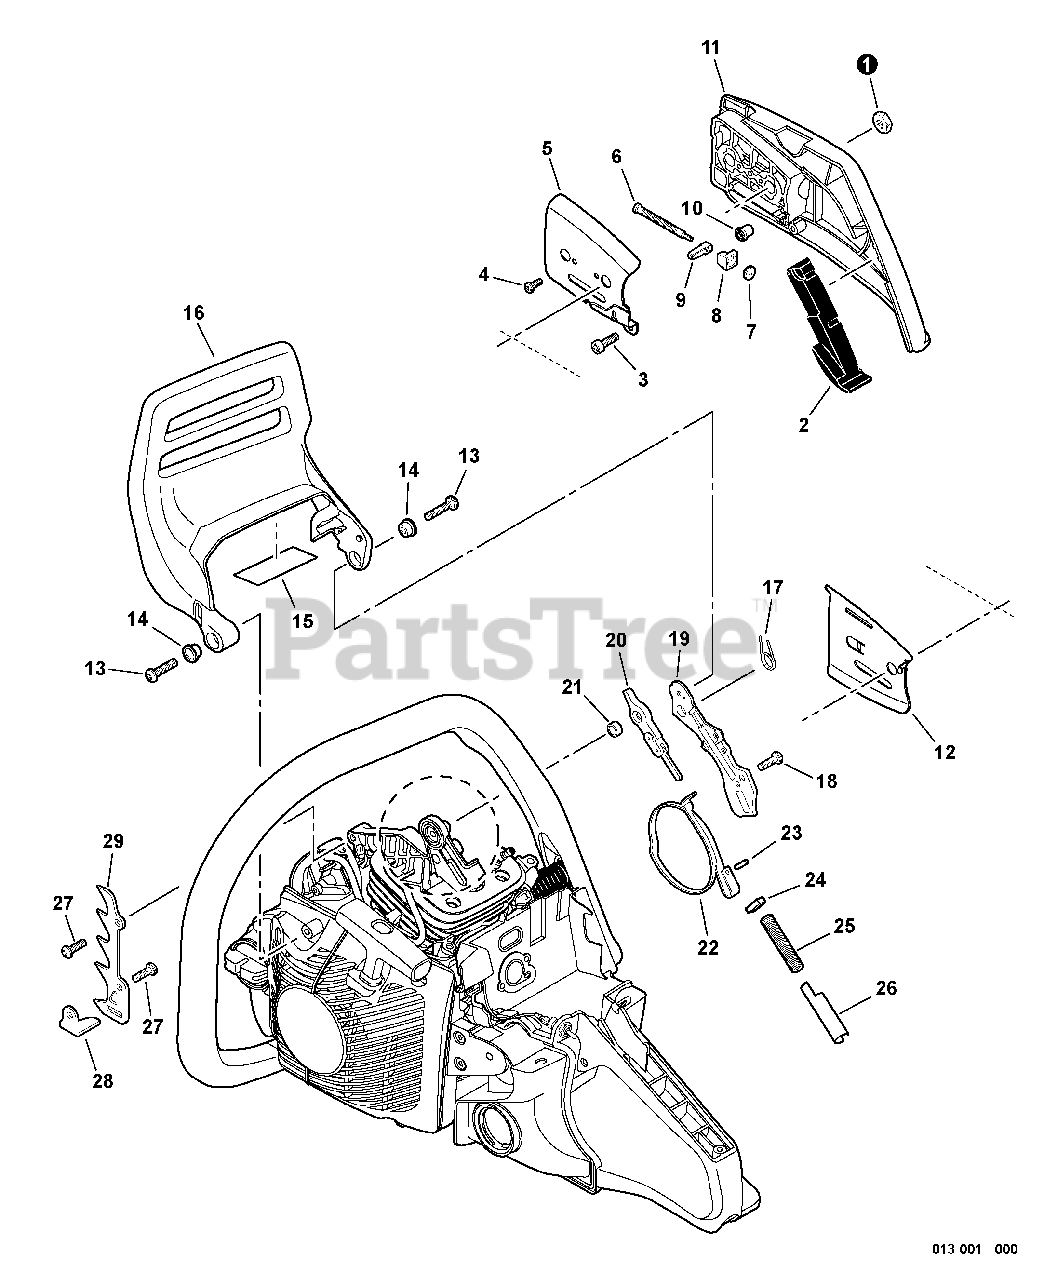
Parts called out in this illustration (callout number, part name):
1	NUT - 8
2	CUSHION
3	SCREW - 4X12
4	SCREW - 3X5
5	PLATE, GUIDE - OUTER
6	SCREW, TENSIONER
7	GEAR - BEVEL
8	COLLAR - 8
9	TENSIONER, CHAIN
10	GEAR - PINION
11	GUARD, SPROCKET
12	PLATE, GUIDE - INNER
13	SCREW - 5X16
15	DEFLECTOR, HEAT
16	LEVER, BRAKE
18	SCREW - 5X16
19	COVER, BRAKE
20	CONNECTOR, BRAKE
22	BAND, BRAKE
26	GUIDE, SPRING
27	SCREW - 5X16
28	CATCHER, CHAIN
29	SPIKE
